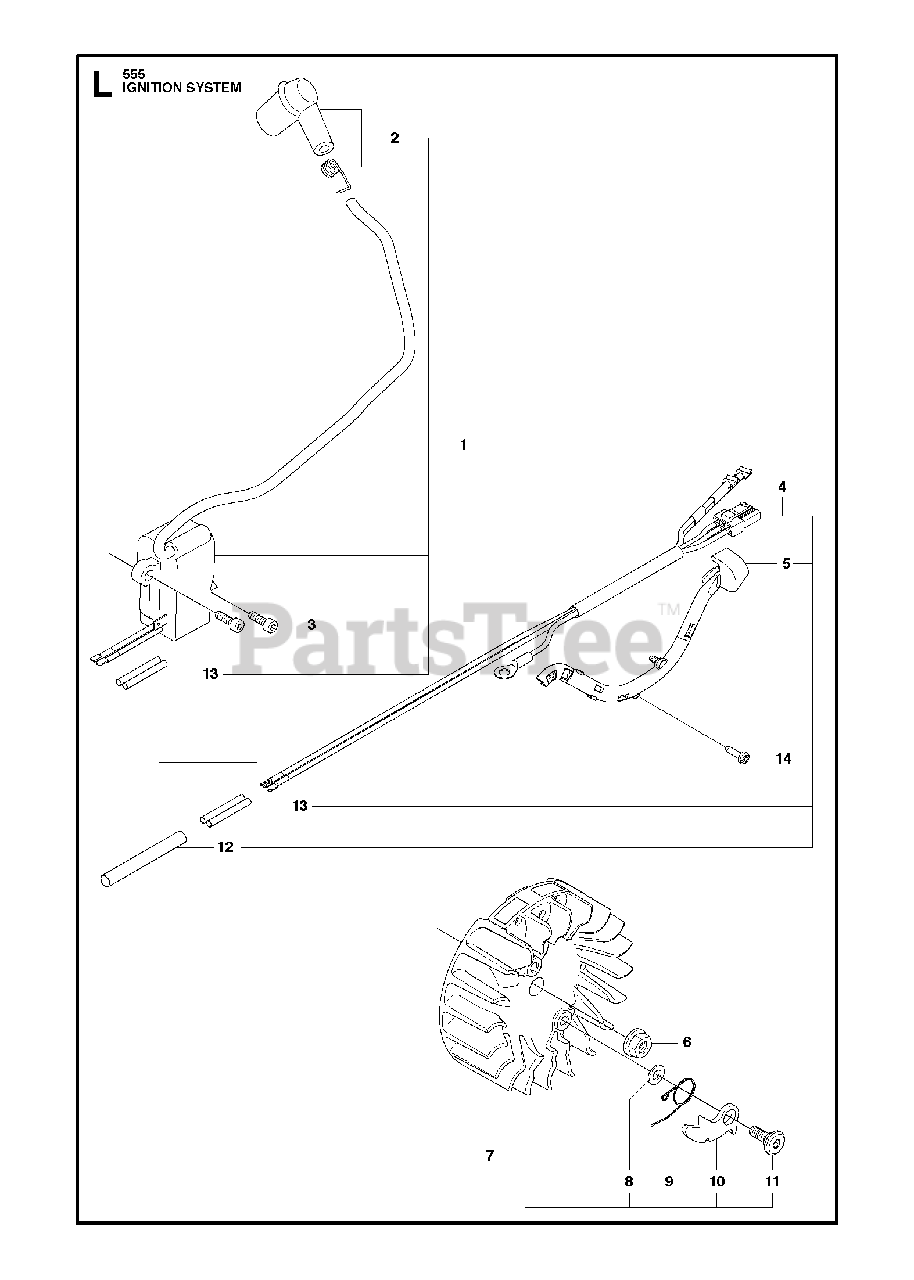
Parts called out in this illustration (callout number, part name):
1	IGNITION MODLUE ASSY
2	SPARK PLUG CAP ASSY
4	WIRING ASSY
5	CABLE HOLDER
6	NUT W/ WASHER
7	FLYWHEEL ASSY
8	WASHER
9	SPRING
10	PAWL
11	SCREW M5X14
12	CABLE COVER
13	SHRINK HOSE
14	SCREW
